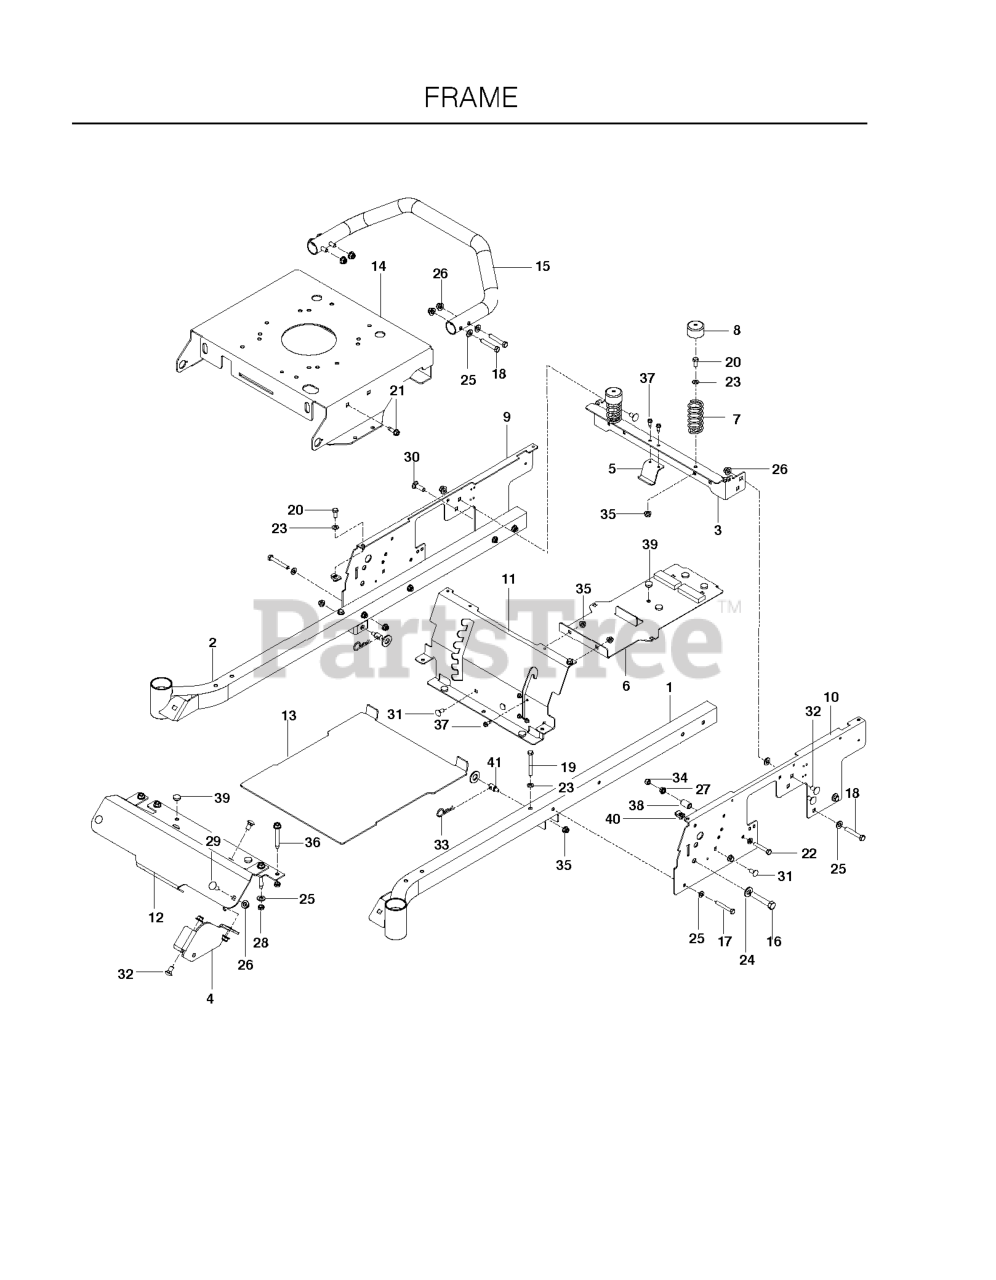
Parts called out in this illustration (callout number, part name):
1	FRAME TUBE, LH, ORG
2	FRAME TUBE, RH, ORG
3	SUPPORT, REAR SEAT, ORG
4	BRACKET, FRONT DECK, BLK
5	HOLDING DEVICE, FUEL TANK, BLK
6	SUPPORT, TANK/BATT, BLK
7	SEAT SPRING
8	SPRING CAP
9	PLATE.LH.SIDE.ORANGE
10	PLATE.RH.SIDE.ORANGE
11	PANEL, SEAT SUPP. ORG
12	FOOT.REST.30/38.ORANGE
13	PLATE, FOOT W/DECALS, HUSQ
14	PLATE, ENGINE, ORG
15	IMPACT BAR, ORG
16	HCS 1/2C X 2 3/4
18	HCS 3/8C X 2 1/4
19	HCS 5/16C X 2-3/4
20	BOLT 3/8-16 X 1.0
22	HCS 5/16-18X2
23	FLAT WASHER 5/16 SAE
24	WASHER 1/2" FLAT
25	WASHER 3/8 SAE FLAT
26	NUT 3/8-16 HEX FLG NYLOC ZD
27	NUT 5/16C WHIZ
28	NUT HEX 3/8-16 NYLON, THIN
29	RHSNB 3/8C X 1
30	RHSNB 3/8-16 X 1-1/4
31	BOLT 5/16C X 3/4" CARRIAGE
32	RHSNB 3/8-16 X 3/4 GR5 ZD
33	HAIRPIN #4
34	NUT 5/16 NYLOC
35	5/16-18 NYLOC FLANGE NUT
36	ENGINE BOLT, SPECIAL
37	SCREW 1/4 X 5/8
39	GROMMET, BUMPER
40	U-CLIP 5/16-18 NUT RETAINER
41	STUD.FASTNER.W/ANTI-ROTATE
